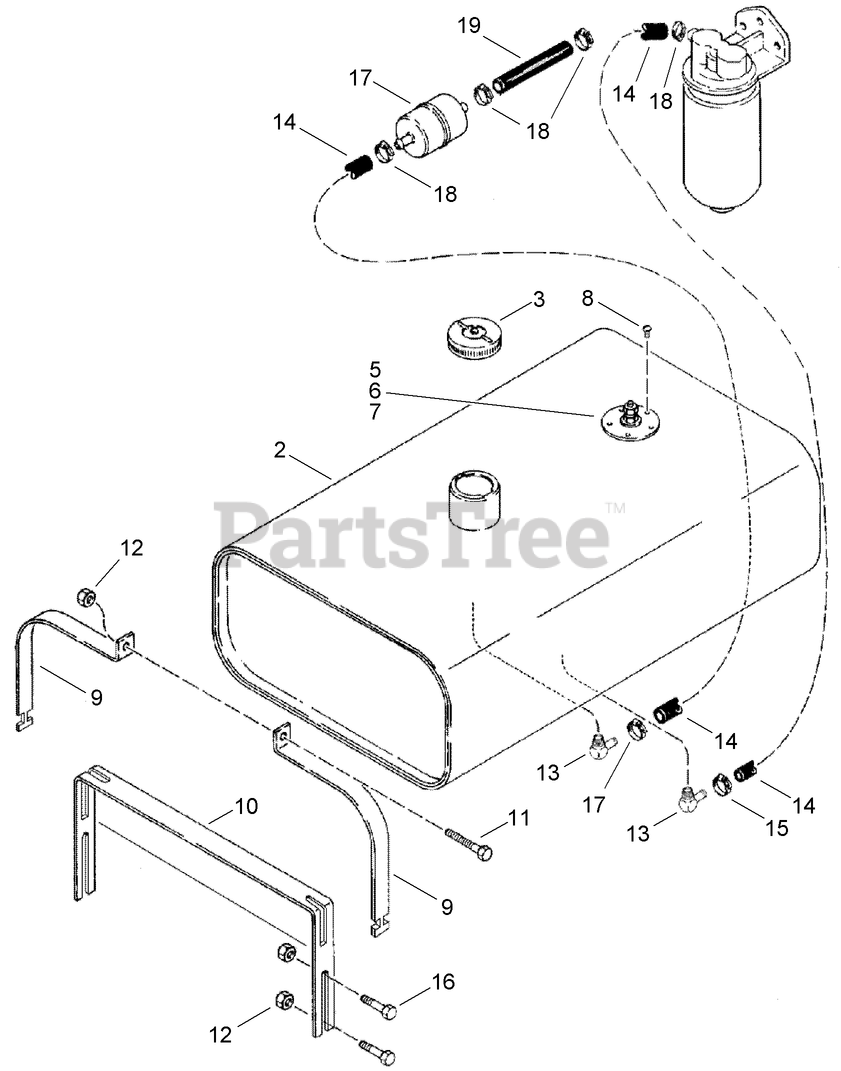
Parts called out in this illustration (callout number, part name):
2	TANK - Fuel
3	CAP - Fuel Tank
5	SENDER - Fuel Tank
6	FLOAT - Sender
7	GASKET - Sender
8	SCREW - Machine, Pan Head Slotted, No. 10 NC x 1/2in
9	HOSE - Fuel Line
10	STRAP - Fuel Tank
11	SCREW, METRIC FLANGE FULL - M8 x 25
12	NUT-TORQUE, PREVAILING
13	STEM-90 (BARB HOSE)
14	TANK ASSEMBLY - Fuel
15	CLAMP-Hose Type M #04
16	SCREW-HH
17	FILTER - Fuel, In-line (Includes Items 18 and 19)
18	CLAMP - Hose (Supplied with Item 17)
19	HOSE - Fuel Line (Supplied with Item 17)
